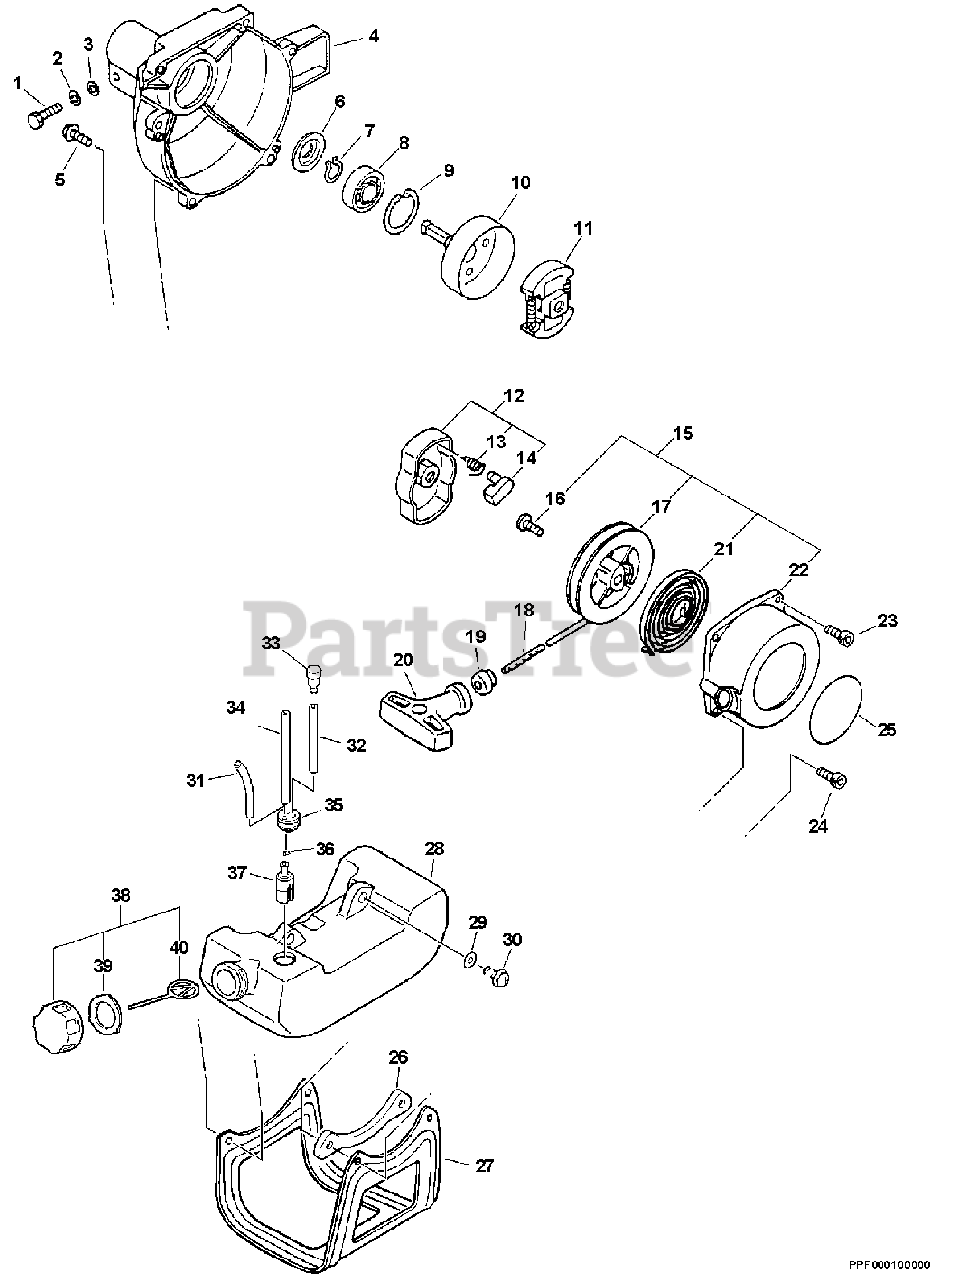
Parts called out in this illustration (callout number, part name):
1	BOLT - 5X25
2	LOCKWASHER - 5
3	WASHER - 5
4	CASE, FAN - ORANGE
5	SCREW - 4X16
6	RETAINER, PIPE
7	RING, RETAINING - 12
8	BEARING, BALL - 6201
9	RING, RETAINING - 32
10	DRUM, CLUTCH
11	CLUTCH ASSY
12	STARTER PAWL ASSY
13	SPRING, RETURN
14	PAWL, STARTER - BLACK
15	STARTER ASSY
17	REEL, ROPE
18	ROPE, STARTER - 3X1000
19	GUIDE, ROPE
20	GRIP, STARTER
21	SPRING, REWIND
22	CASE, STARTER
23	SCREW - 4X16
24	SCREW - 4X20
25	LABEL - ECHO
27	GUARD, FUEL TANK
28	FUEL TANK ASSY
29	WASHER - 5
30	SCREW - 5X20
31	PIPE - 3X6X90 -- CLEAR
32	PIPE - 3X5X70 -- BLACK
33	VENT, FUEL TANK
34	PIPE - 3X5X180 -- BLACK
35	GROMMET
36	CLIP - 6
37	FILTER, FUEL
38	CAP ASSY - ORANGE
39	GASKET, CAP
40	CONNECTOR, CAP
